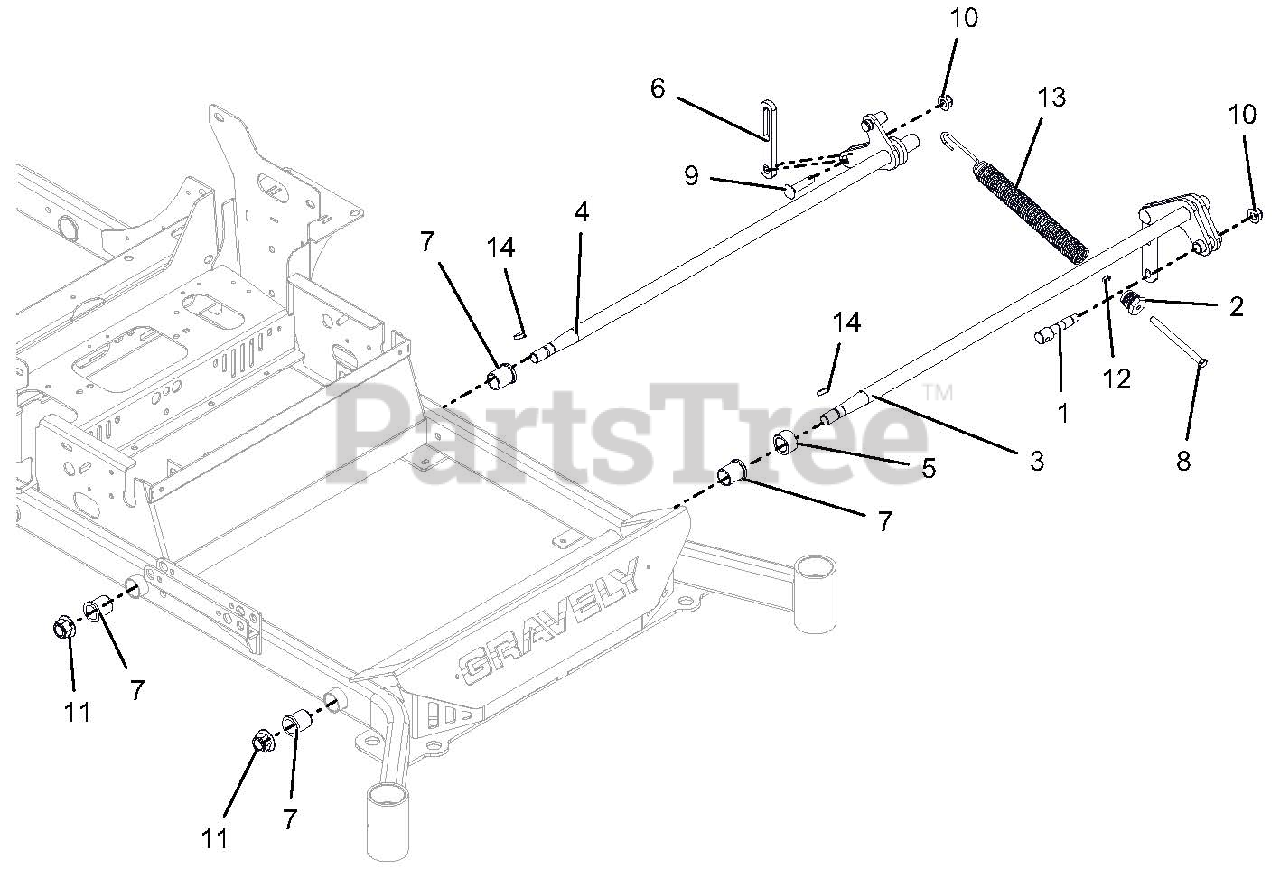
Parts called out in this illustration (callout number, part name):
1	TRUNION, SPRG
2	PLUG, SPRG
3	WLDMT, FRONT LH DECK LIFT ARM
4	WLDMT, REAR LH DECK LIFT ARM
5	SPACER, 1.500 X 1.000 X .880
6	LINK, DECK LIFT - LONG
7	BSHG-FLG 1.00X1.25X1.5X1.5
8	BLT-HEX .38-16X5.00 GR5 YWZC
9	BLT-RDHDSQNK .50-13X2.25 G5 Y
10	NUT-LK-NYL-FLG .50-13 YWZC
11	NUT-LK-NYL-FLG .75-10 YWZC
12	NUT, JAM .375-16 YWZC
13	SPRG, DECK LIFT
14	KEY, WDRF .25 X 1.00 HRD #15
